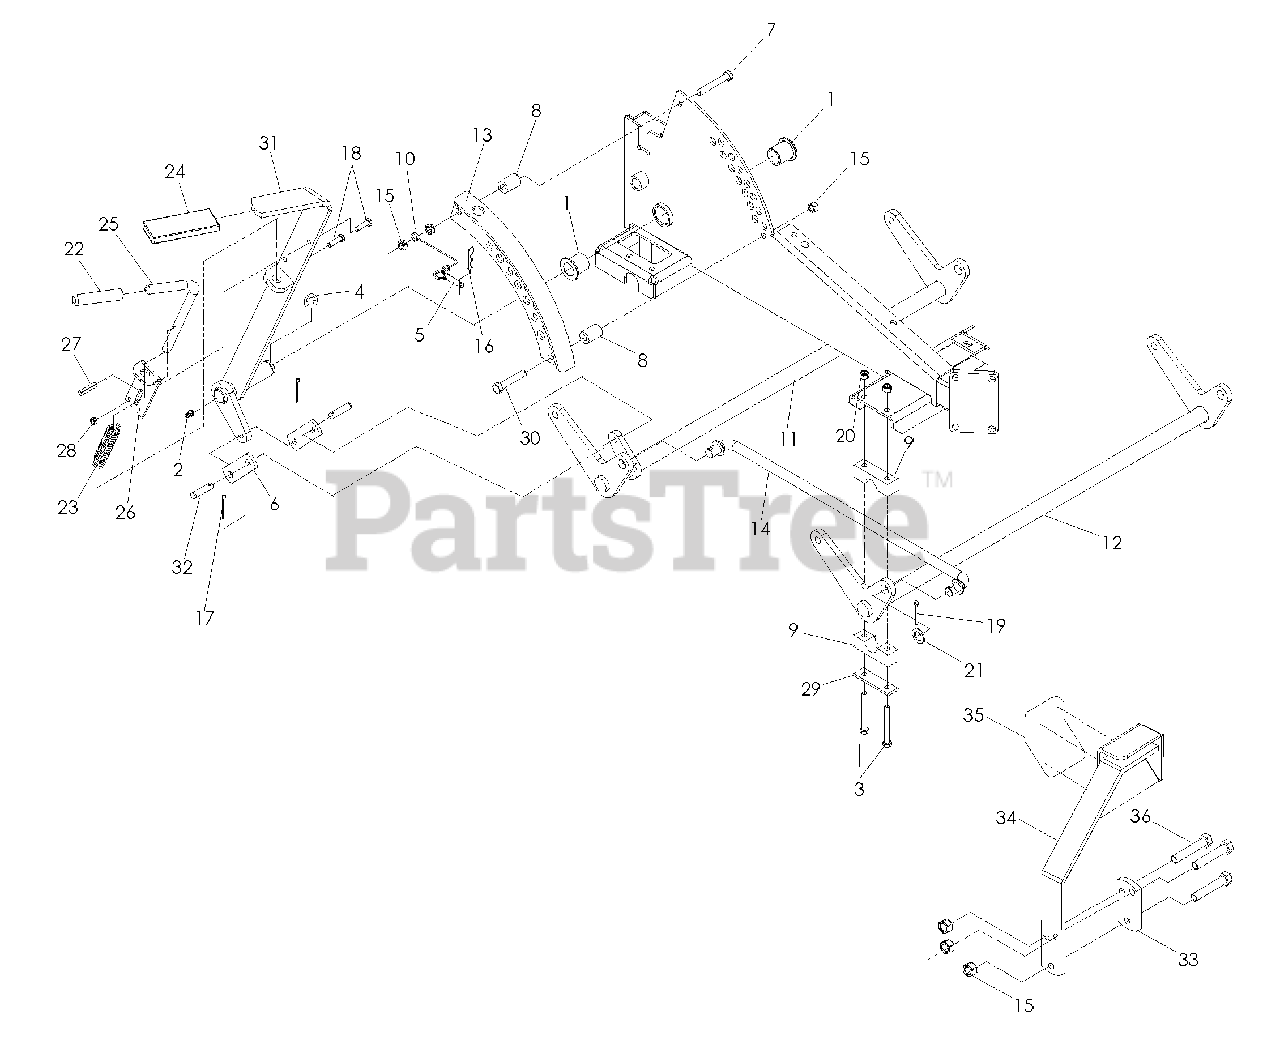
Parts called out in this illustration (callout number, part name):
3	HCS 5/16-18 x 2 3/4
4	E-RING 7/8
5	PIN LIFT 1/2 x 2 w/RINGS
7	HCS 3/8-16 x 2 3/4
9	BLOCK, PILLOW
11	SHAFT, REAR LIFT
12	SHAFT, FRONT LIFT
13	PLATE, ADJUSTMENT
14	CROSS LINK
15	NUT 3/8-16 HEX NYLOC
16	PIN, HAIR .120 x 2 1/2
17	PIN, COTTER 1/8 x 3/4
18	HCS 1/4-20 x 3/4
19	PIN, COTTER, 5/32 x 1 1/4
20	NUT 5/16-18 HEX NYLOC
22	GRIP, VINYL
23	SPRING, COMPRESSION
24	GRIP, LIFT LEVER
25	L PIN, 1/2 x 6.69
27	PIN, GROOVED 3/16 x 1 1/4
28	NUT 1/4-20 CENTERLOCK
29	REINFORCED BAR
30	HCS 3/8-16 x 2 1/2
31	LIFT LEVER
32	PIN, CLEVIS 3/8 x 1 1/8
32	FOOT ASSIST - NOT ON ALL MODELS
33	TIGHTING PLATE
34	LIFT PEDAL
35	ANTI-SKID PAD
36	HCS 3/8-16 x 1 1/2
